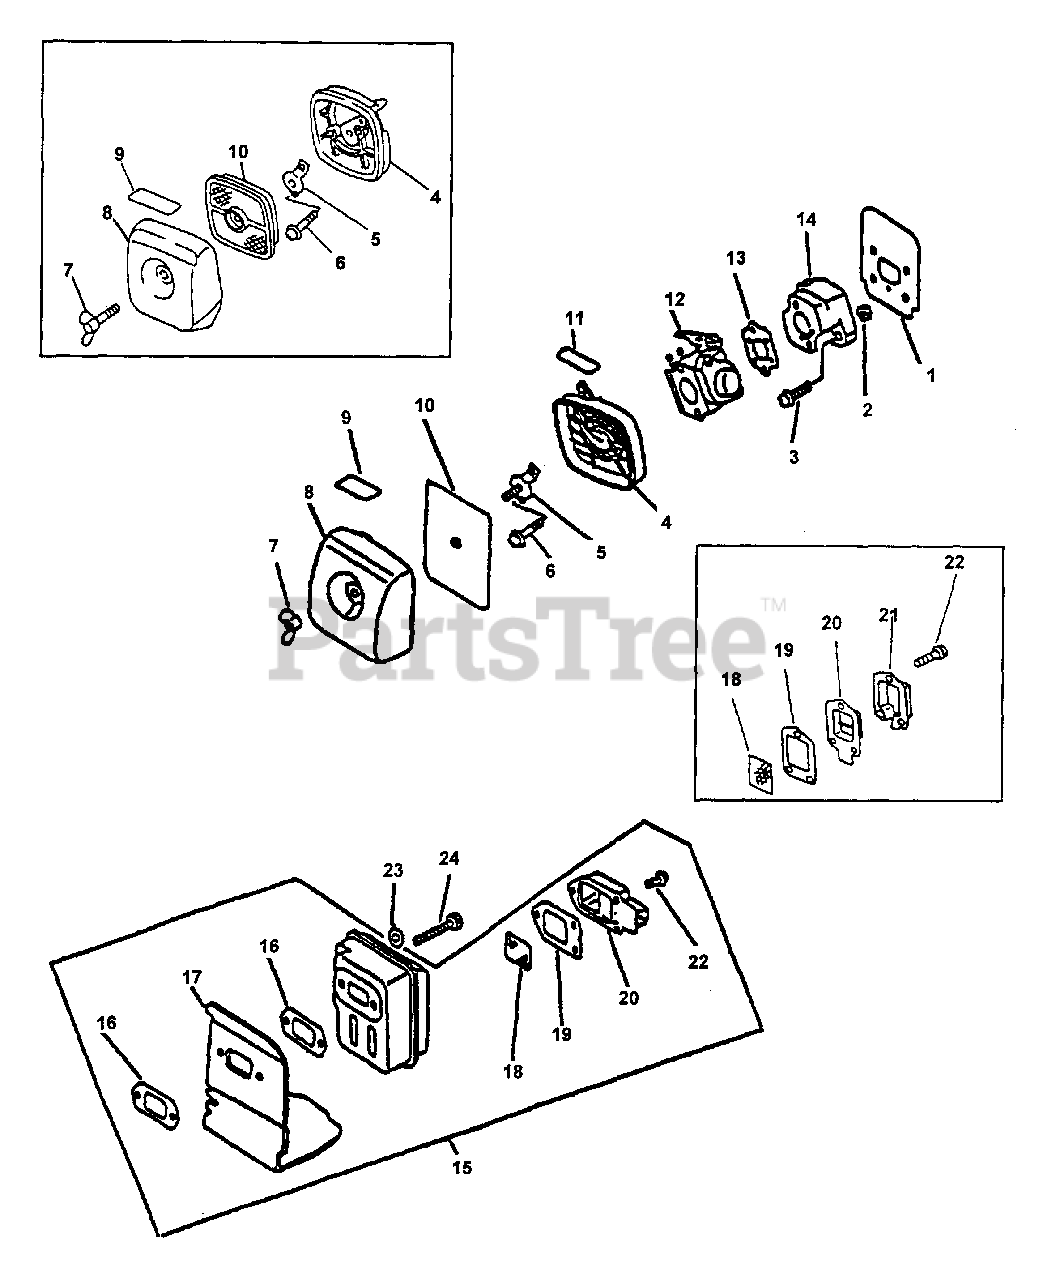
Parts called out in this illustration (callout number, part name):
1	SHIELD, INTAKE
3	SCREW - 5X20
4	AIR FILTER CASE ASSY
5	PLATE, PREVENT
6	SCREW - 5X65
7	WINGNUT - 6
7	THUMBSCREW
8	COVER, AIR FILTER
8	COVER, AIR FILTER - GRAY
9	LABEL - TOP
10	FILTER, AIR
10	FILTER, AIR - SINGLE LAYER
11	LABEL - CHOKE
12	CARBURETOR C1U-K29
12	CARBURETOR C1U-K47
13	GASKET, INTAKE
14	INSULATOR, INTAKE
15	MUFFLER ASSY
16	GASKET, EXHAUST
17	COVER, EXHAUST
18	SCREEN, SPARK ARRESTOR
19	GASKET, EXHAUST
20	GUIDE, EXHAUST - OUTER
21	GASKET, EXHAUST - INNER
22	SCREW - 4X10
23	WASHER - 5
24	SCREW - 5X55
